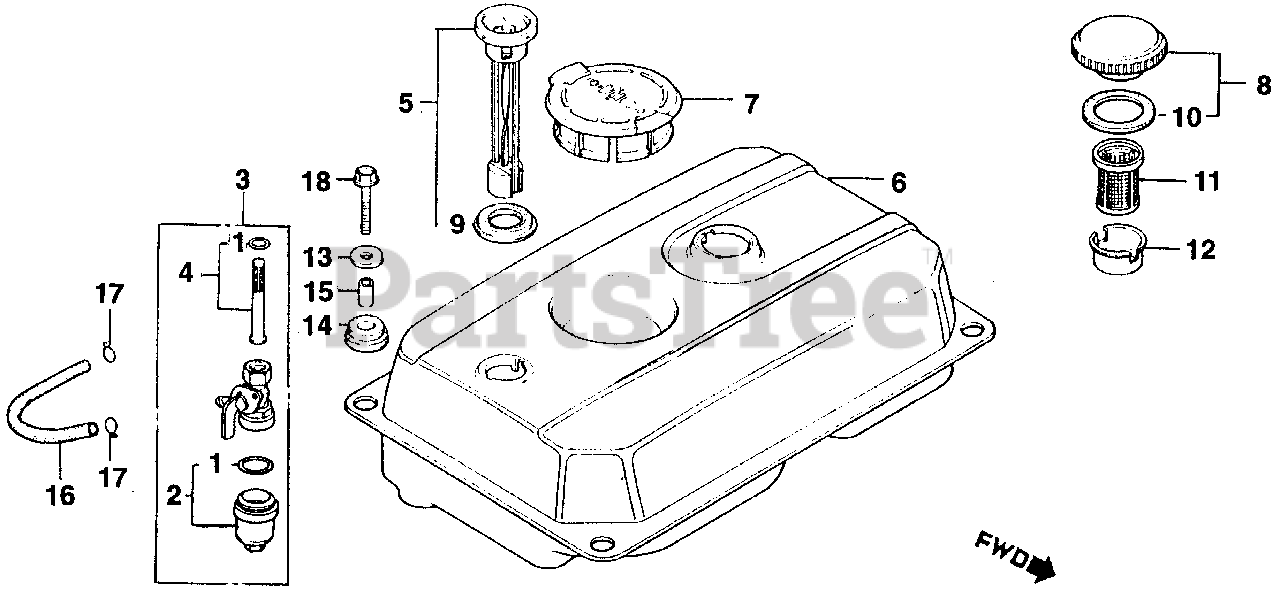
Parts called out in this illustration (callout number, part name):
1	GASKET SET, PETCOCK (CONTAINS 1 LARGE & 1 SMALL. USE AS NEEDED)
2	CUP, FUEL STRAINER
3	PETCOCK ASSY.
4	SCREEN SET
5	METER, FUEL
6	TANK, FUEL *NH31* (MCKINLEY WHITE)
7	CAP, SPARK PLUG HOLE
8	CAP, FUEL FILLER
9	GASKET C, FUEL METER
10	GASKET, FUEL FILLER CAP
11	FILTER, FUEL
12	HOLDER, FUEL FILTER
13	WASHER, TANK RUBBER
14	CUSHION, TANK RUBBER
15	COLLAR, TANK RUBBER
16	BULK HOSE, FUEL (4.5X3000) (4.5X105)
17	CLIP, TUBE (B8)
18	BOLT, FLANGE (6X25)
